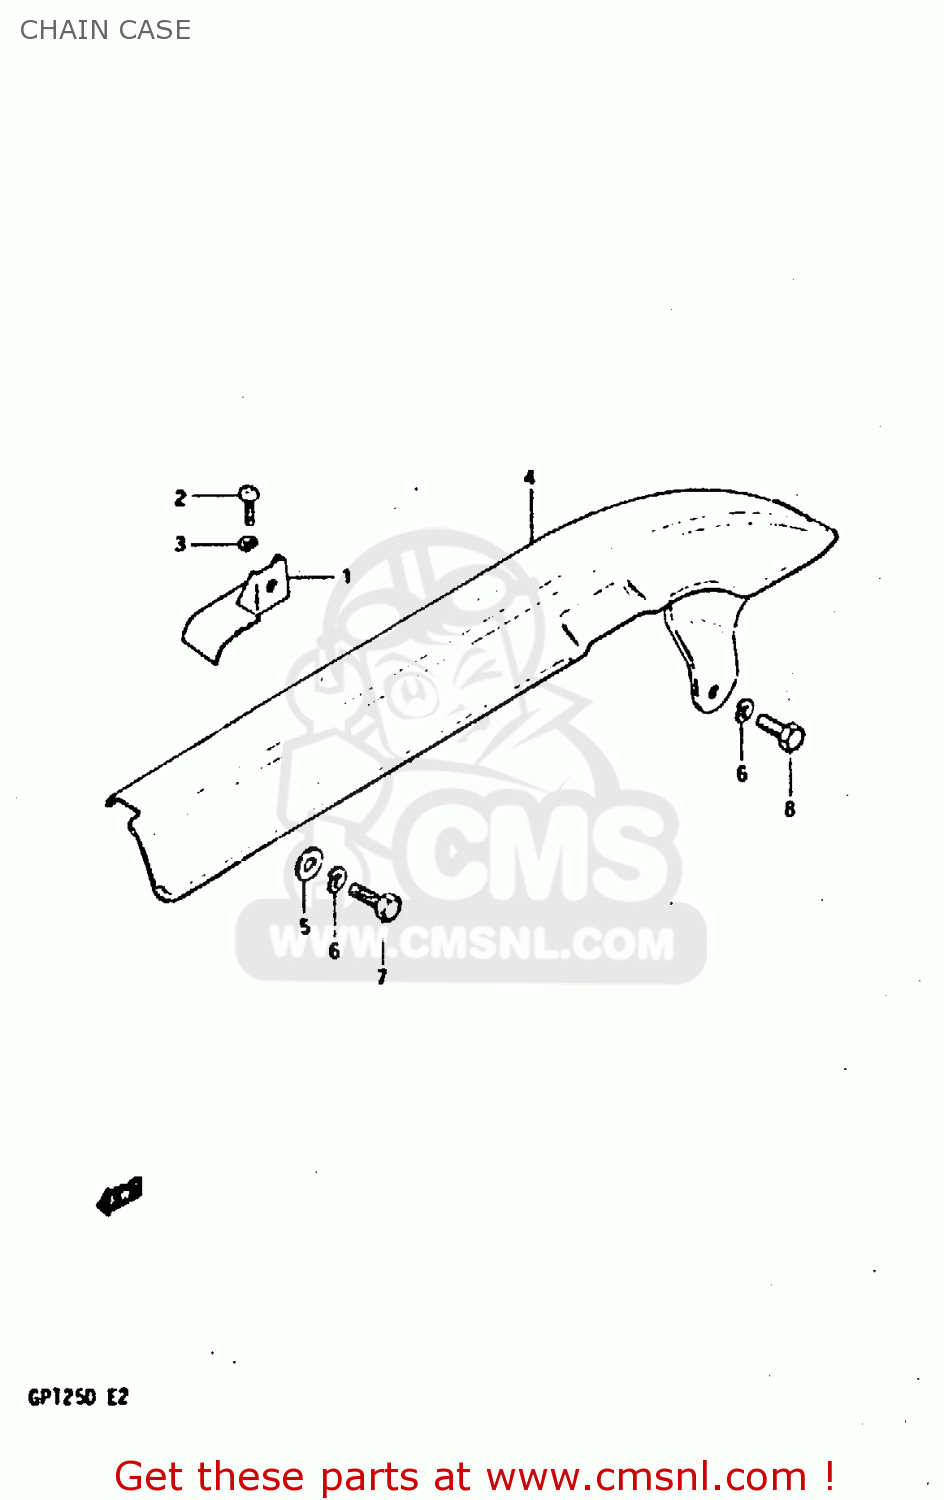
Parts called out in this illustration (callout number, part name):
1	BRACKET, CHAIN CASE FRONT
2	SCREW
3	LOCK WASHER
4	CASE,CHAIN
5	WASHER
6	LOCK WASHER
7	BOLT
8	BOLT
